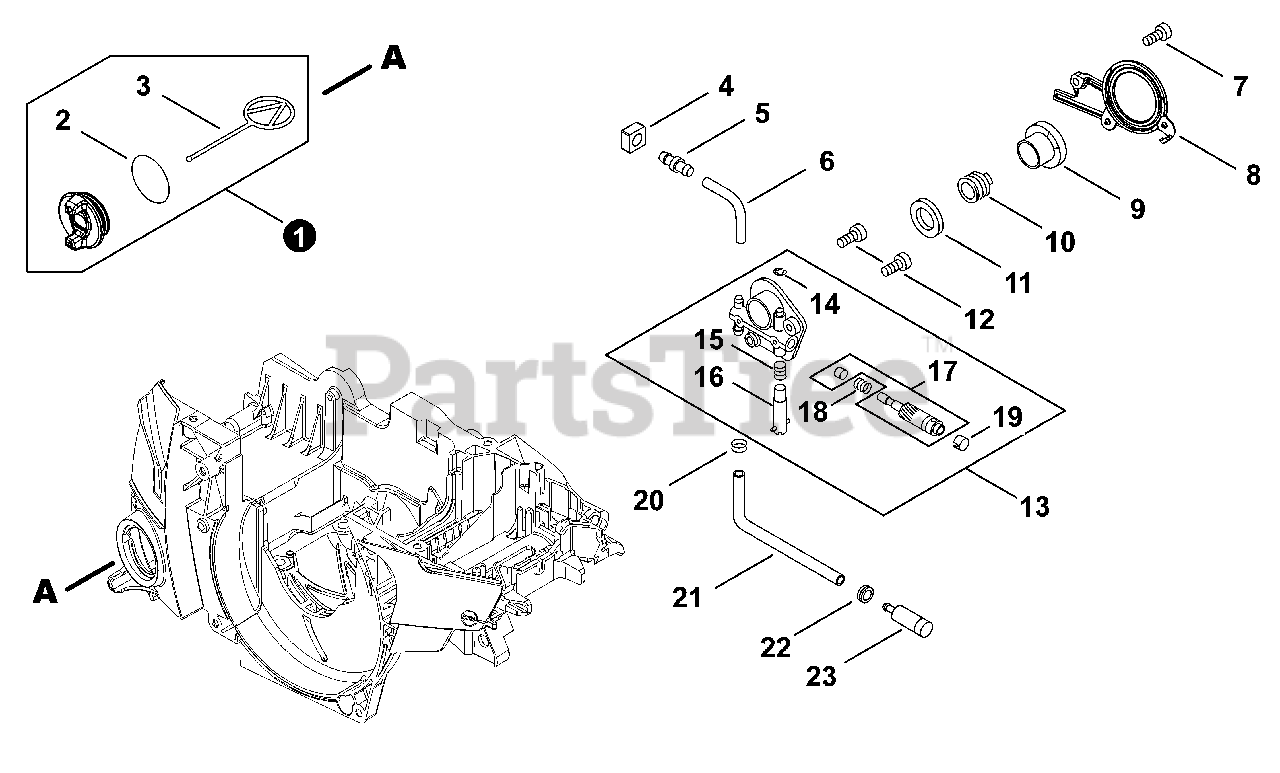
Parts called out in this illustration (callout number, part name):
1	CAP ASSY, OIL
2	O-RING 29
3	CONNECTOR, CAP L= 60 MM
5	CONNECTOR, PIPE
6	PIPE 3×6×49
7	BOLT, TORX 4×12
8	COVER, OILER
9	COLLAR 10
10	GEAR, WORM
11	WASHER 10.5×17.4×1.8
12	BOLT, TORX 5×12
13	AUTO-OILER ASSY
16	ADJUSTER, OILER
17	PLUNGER ASSY
19	CAP, PLUNGER
20	CLIP Ø6.5 MM
21	PIPE 3×6×200
22	GROMMET
23	FILTER, OIL
